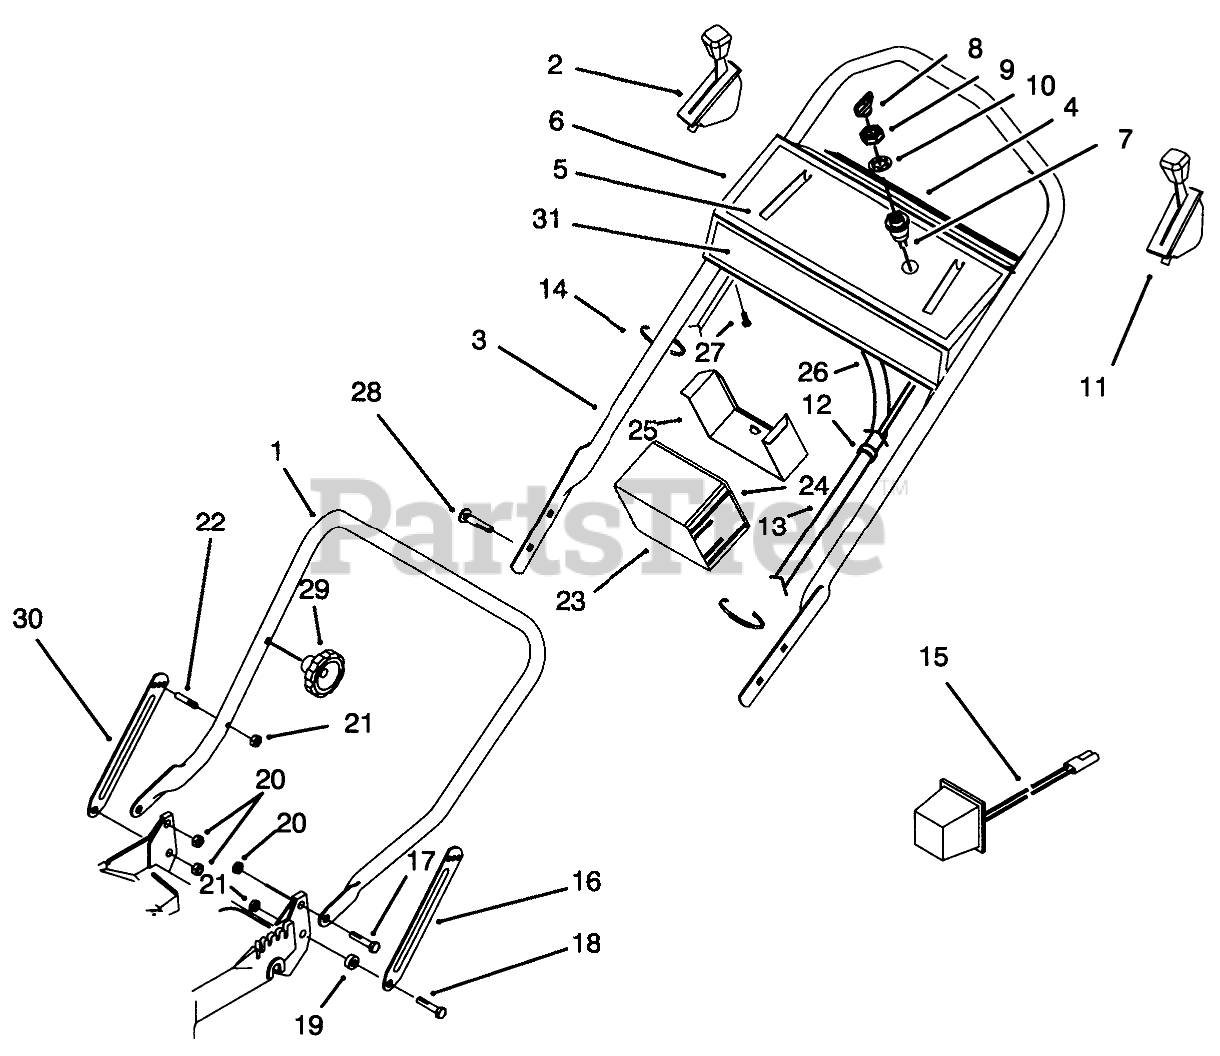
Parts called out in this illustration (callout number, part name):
1	LOWER HANDLE ASM
2	CONTROL-SPEED, GROUND
3	UPPER HANDLE, PVC DIP
4	DECAL - PANEL, REAR
5	DECAL - INSTRUCTION
6	Panel-Control (Incl. Ref. #4 & 5)
7	STARTER SWITCH ASM
8	KEY-IGNITION
9	NUT-HH
10	WASHER-TOOTH, INTERNAL
11	THROTTLE CONTROL
12	FITTING-RING
13	CONTROL CABLE COVER
14	TIE-CABLE
15	Charger
16	LH HANDLE LATCH
17	SCREW-SHOULDER
18	SCREW-SHOULDER
19	SPACER
20	NUT-LOCK, NI
21	NUT-LOCK, NI
22	HANDLE PIN
23	BATTERY ASSEMBLY
24	DECAL - BATTERY
25	Retainer-Battery
26	Harness-Wire
27	10-16X1/2 SHWH SCREW
28	5/16-18 X 2 HNDLE SCREW
30	RH HANDLE LATCH
31	DECAL - PANEL
